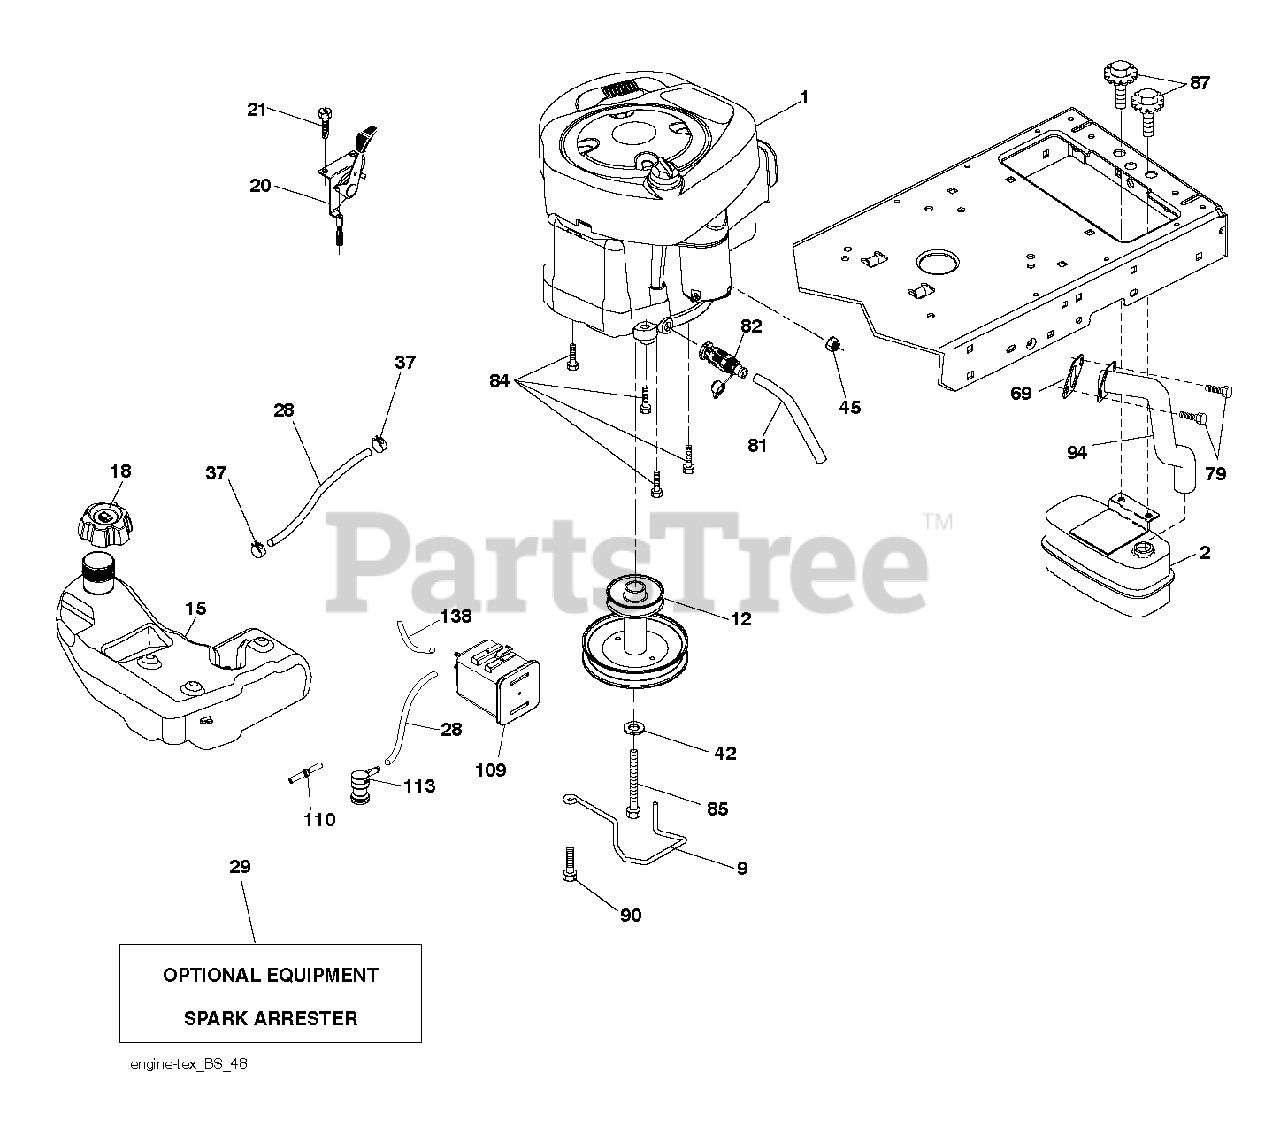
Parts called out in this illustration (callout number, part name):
2	MUFFLER.SINGLE.LRG.BRIGGS.KOHL
9	KEEPER.BELT.ENGINE
12	Engine Pulley
15	TANK ASM.FUEL.3
18	Fuel Cap Assembly, 3" Black
21	SCREW.#10 X 0.750.BOS (2 2)
28	LINE.FUEL.20"FRONT.EMI
29	KIT.SPARK ARRESTOR(392390 B&S)
37	HOSE CLAMP
42	LOCKWASHER
45	NUT
79	SCREW.SOCKET HD.5/16-1
81	TUBE, DRAIN OIL ASM.
82	VALUE.OIL.DRAIN
84	SCREW.3/8-16
85	BOLT HEX 7/16-20X4-1/4"
87	BOLT, 5/16-18 X 1 3/4
90	SCREW 3/8-16X1
94	Exhaust Tube, B&S 28/31
109	CANNISTER, CARBON
110	VALVE.ASM.ANTI-SLOSH
113	VALVE.SLANT.CARTRDG.90 DEG.TEX
138	PURGE.LINE.36"REAR.CALIFORNIA
